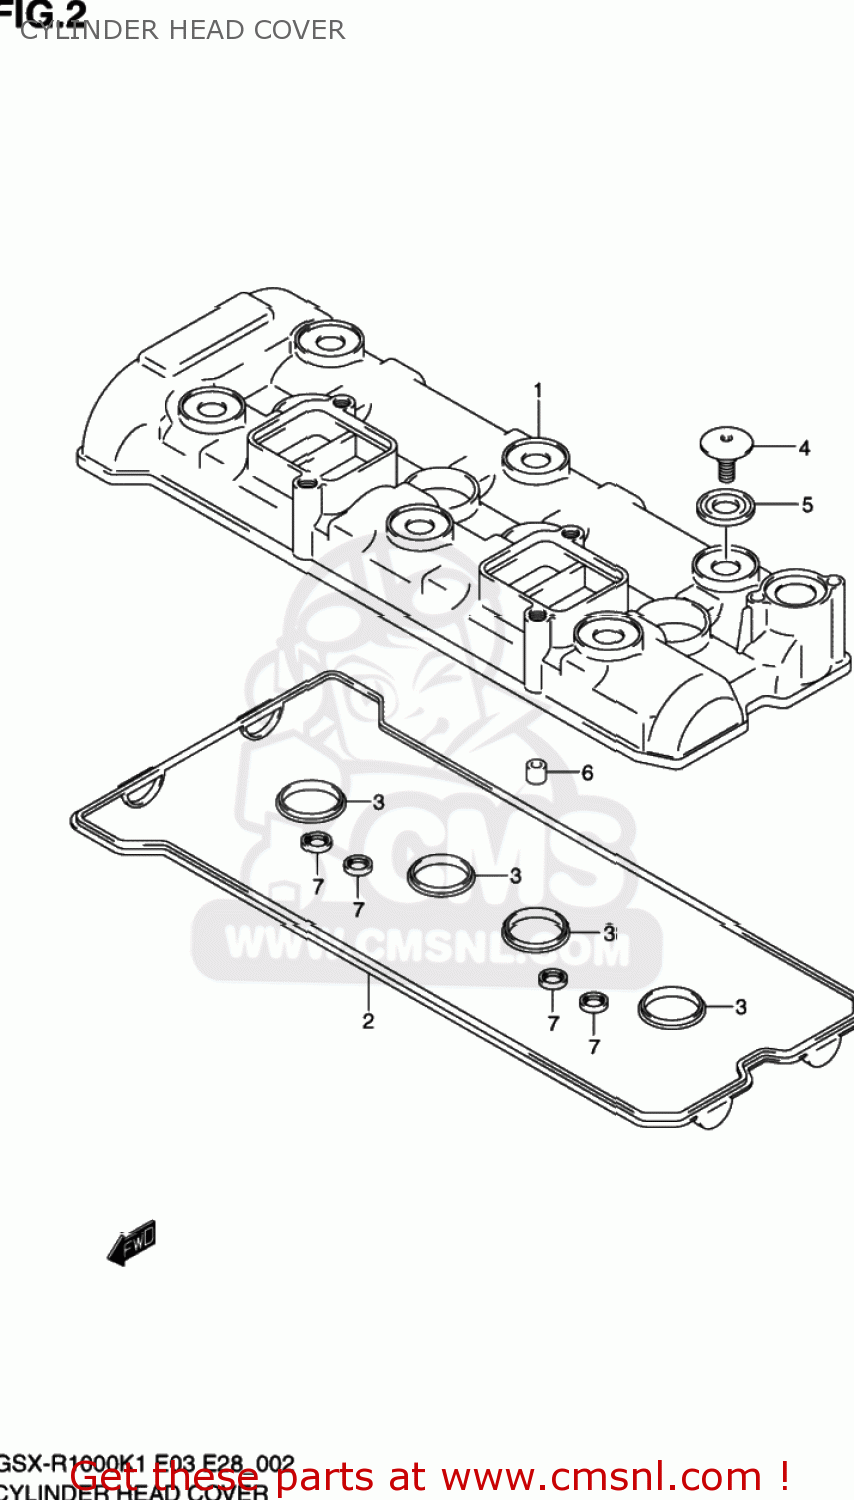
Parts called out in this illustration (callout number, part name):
1	COVER,CYLINDER HEAD
2	GASKET,CYL HEAD COVER NO.1 (NAS)
3	GASKET,CYL HEAD COVER NO.2
4	BOLT(7X17.5)
5	WASHER(10.6X25.5X2.3)
6	PIN(6.2X8X16)
7	GASKET,2ND AIR PASSAGE (NAS)
